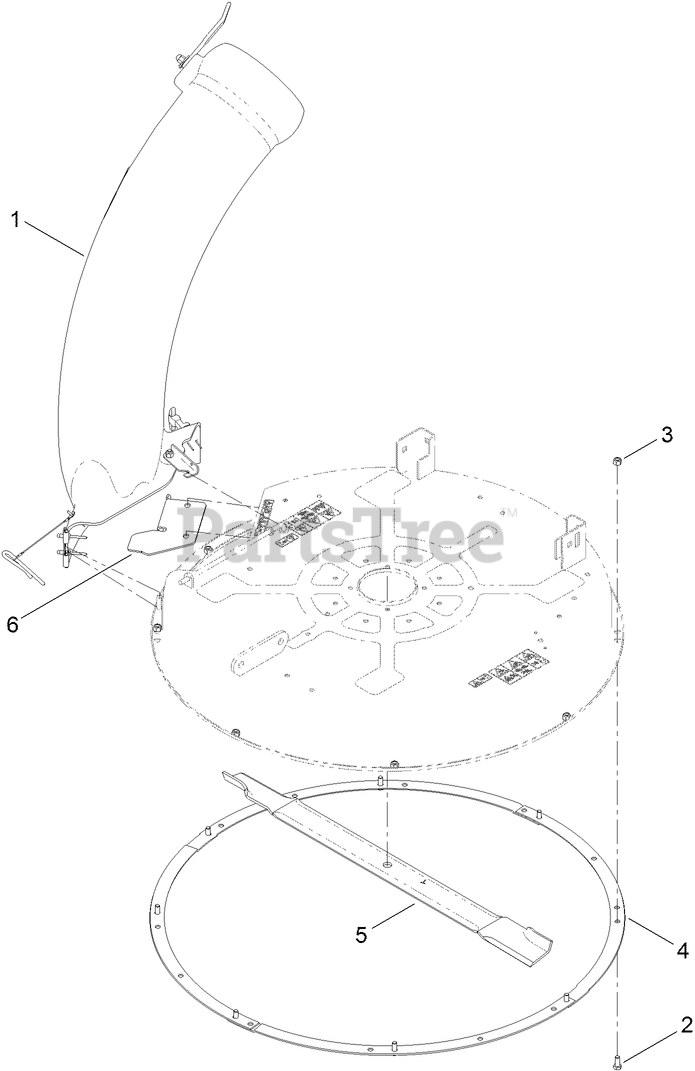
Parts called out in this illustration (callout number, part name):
1	32 INCH CHUTE ASM
2	SCREW-HH
3	NUT-LOCK, NI
4	RING-DECK
6	BRACKET-CUTOFF
